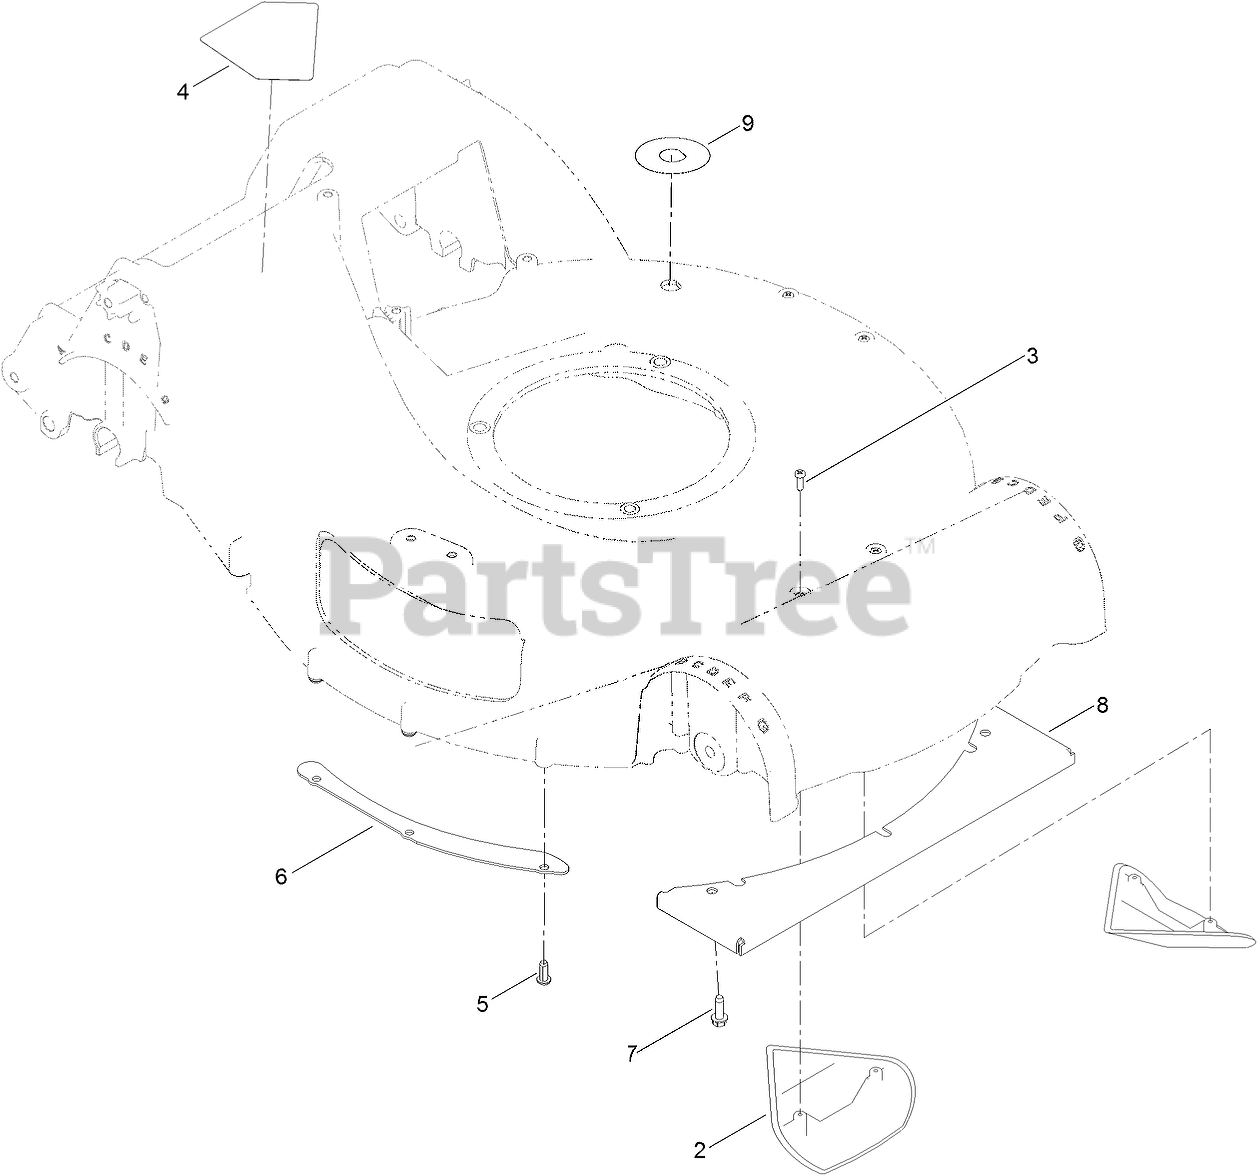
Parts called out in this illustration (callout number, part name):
2	KICKER-HOUSING
3	SCREW-PPH
4	DECAL-DANGER
5	SCREW
6	SHEET-LIP
7	SCREW-HWHTF
8	PLATE-COVER, FRONT
9	DECAL-QUICK WASH
